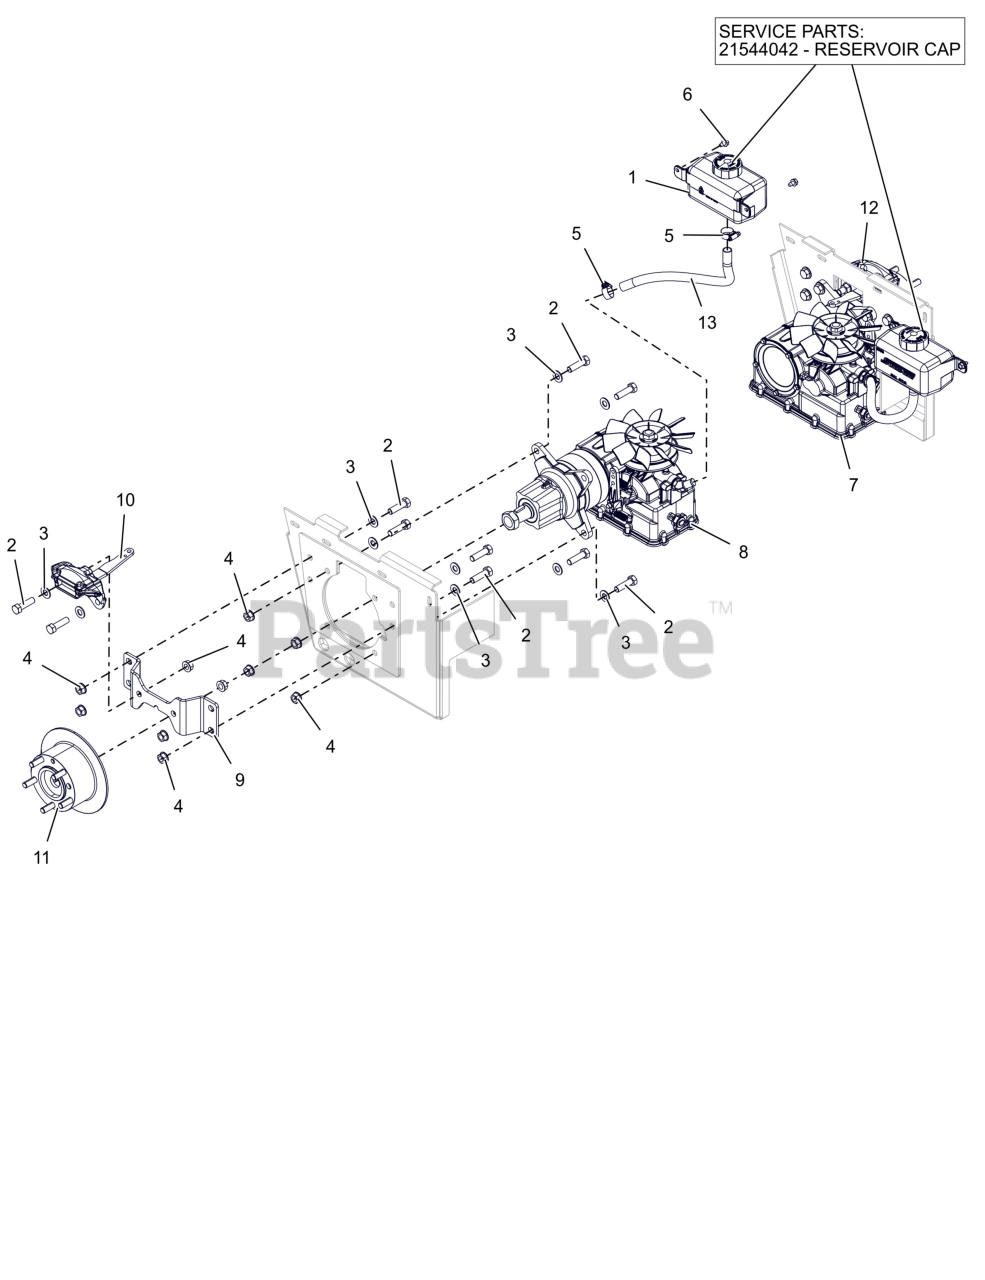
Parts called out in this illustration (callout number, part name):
1	TANK, HYD 1000ML
1	CAP, HYDRO RESERVOIR REPLAC.
2	BLT- HEX .50-13 X 1.75 G8 ZCC
3	WSHR, FLT .557X1.040X.102 ZCC
4	NUT, FLG-CTR LK .500-13 GG ZCC
5	CLAMP,.88 DIA. HOSE
6	SCR,TAP .312-18X.50 HWH TR ZCC
7	TRANSAXLE, LH PARKER HTG13/30
8	TRANSAXLE, RH PARKER HTG13/130
9	BRKT, CALIPER MTG (RED)
10	BRAKE, CALIPER RH
11	ROTOR, BRAKE W/STUDS
12	BRAKE, CALIPER LH
13	HOSE PT500 TRANSAXLE OVERFLOW
